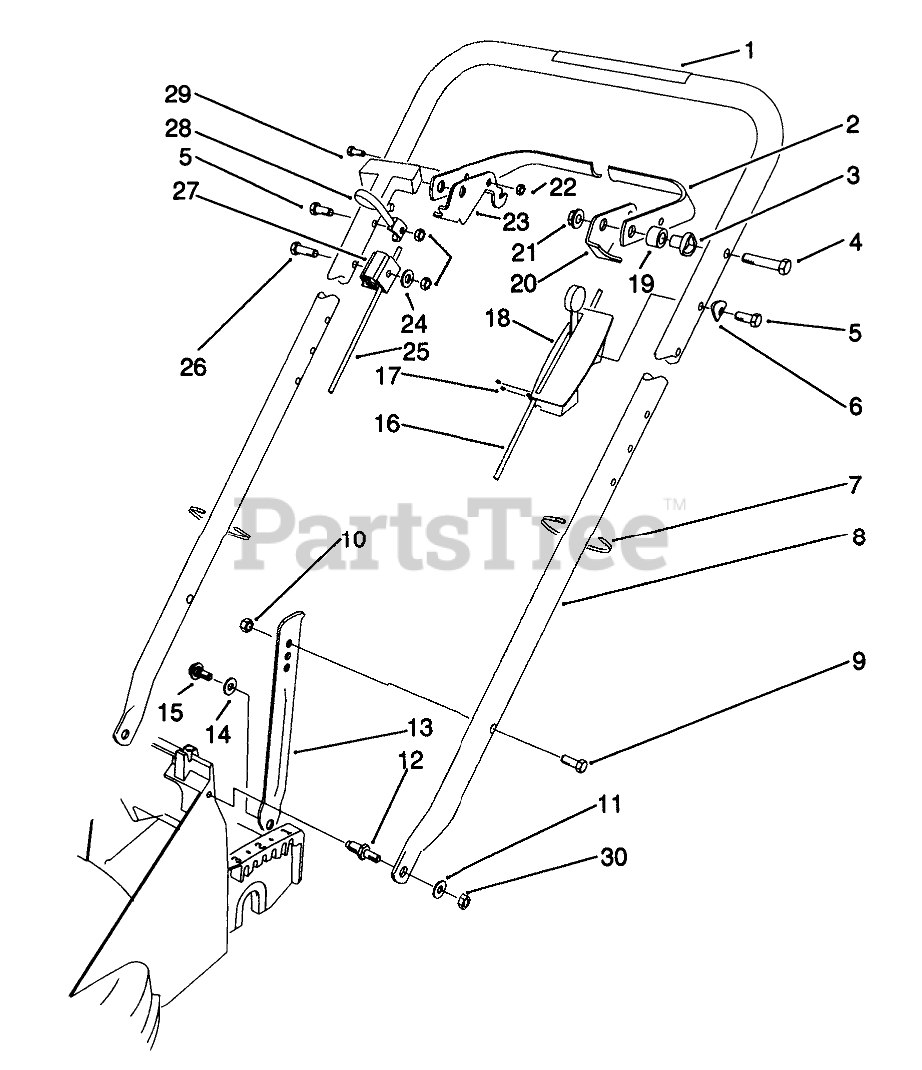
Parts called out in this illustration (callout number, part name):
1	WARNING DECAL
2	Bar-Control
3	SPACER-SUPPORT
4	SCREW-HH
5	SCREW-HH
6	WASHER
7	TIE-CABLE
8	Handle (Incl. Ref. #1)
9	SCREW-HH
10	NUT-LOCK, NI
11	WASHER-PLAIN
12	SHOULDER STUD SCREW
13	HANDLE LATCH B
14	NYLON WASHER
15	SCREW-SHOULDER
16	CABLE-THROTTLE
17	E-RING
18	CONTROL-THROTTLE
19	SPACER-NYLON
20	LEVER-CONTROL
21	NUT-LOCK, NI
22	NUT-LOCK, NI
23	LEVER-CONTROL
24	WASHER-FLAT
25	BRAKE CABLE
26	SCREW-HH
27	SUPPORT-CABLE
28	GUIDE-ROPE
29	SCREW-HH
30	NUT-LOCK, NI
